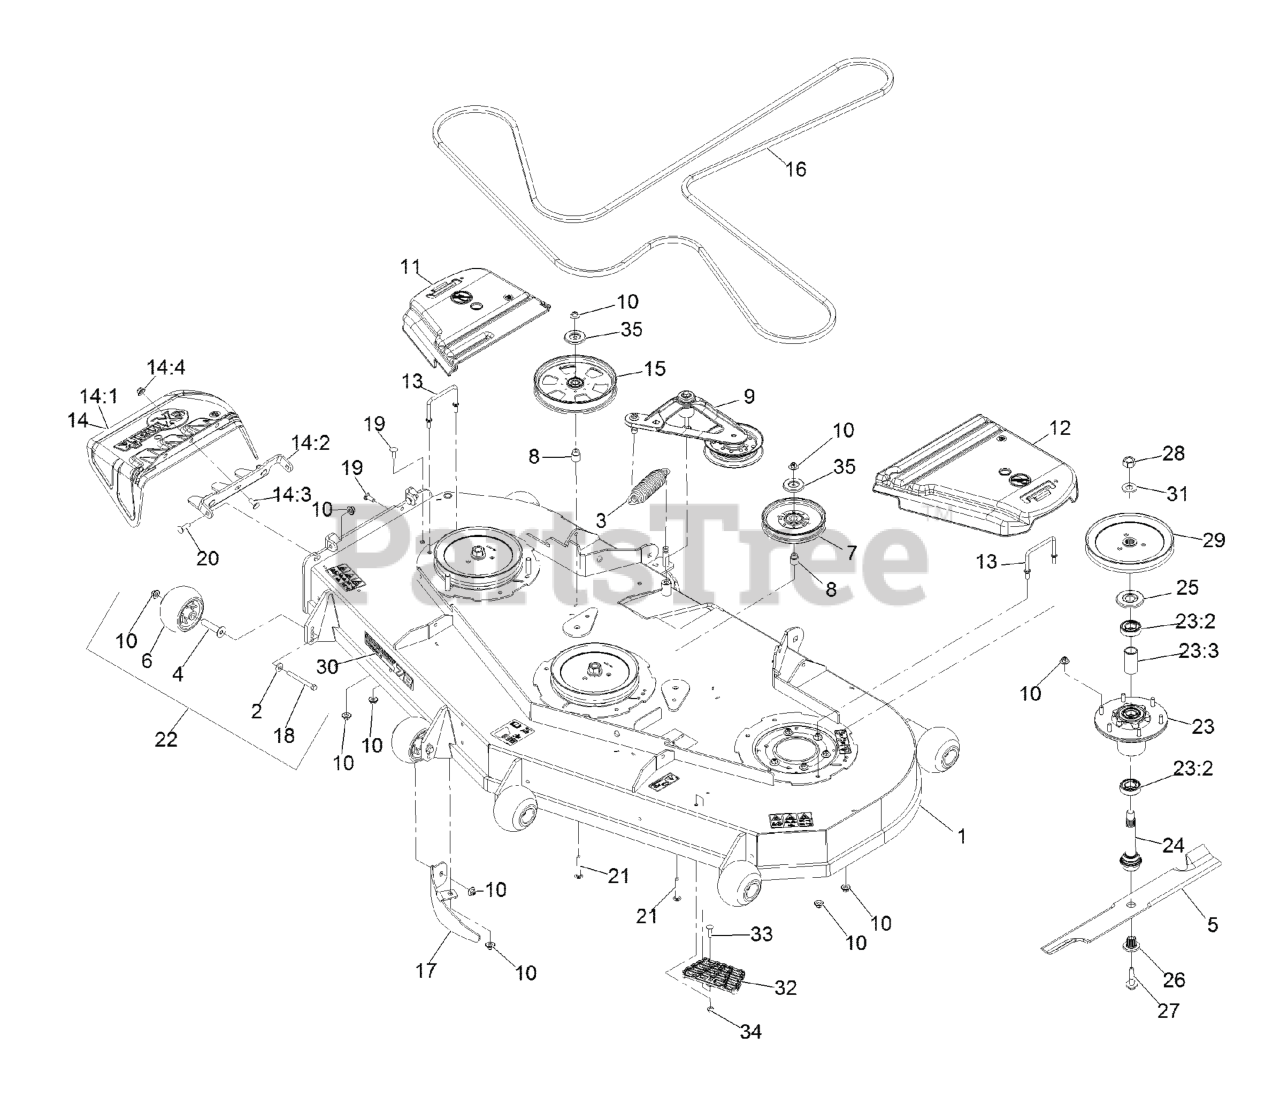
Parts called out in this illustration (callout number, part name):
1	ASM,DECK W/DECALS 724
2	WASHER-BELLEVILLE
3	SPRING-EXTENSION
4	AXLE, ROLLER
6	ROLLER-SCALP, ANTI
7	IDLER-PULLEY
8	BUSHING-IDLER
9	DECK IDLER ASM
10	Nut-Nyloc 3/8-16 Flg
11	COVER-BELT, RH
12	COVER-BELT, LH
13	WIREFORM-COVER
14	ASM,DISCHARGE CHUTE
14:1	CHUTE,DISCHARGE
14:2	BRACKET,DISCHARGE CHUTE
14:3	SCREW-CARR
14:4	Nut-Nyloc 3/8-16 Flg
15	PULLEY-IDLER, FLAT
17	BAFFLE-DOGLEG, LZ72
18	SCREW-HH 3/8-16 X 3 3/4 GR 8
19	SCREW-CARR
20	Bolt-Carriage 3/8-16 X 1 1/4
21	SCREW-CARR
22	KIT, ANTI-SCALP ROLLER
23	ASM-CUTTER HSG WITH BEARINGS
23:2	BEARING-BALL
23:3	SPACER-BEARING
24	ASM-SPINDLE AND SEAL
25	GUARD,BEARING TOP .989
26	BUSHING,SPLINED
27	SCREW,SEMS 1/2-20 X 2.19
28	NUT-HEX
29	SHEAVE,BLADE DRIVE 8.74
30	DECAL, 724
32	STEP-DECK
33	Bolt-Carriage 5/16-18 X 1 1/4
34	NUT-HF, NI
35	SHIELD-DUST
